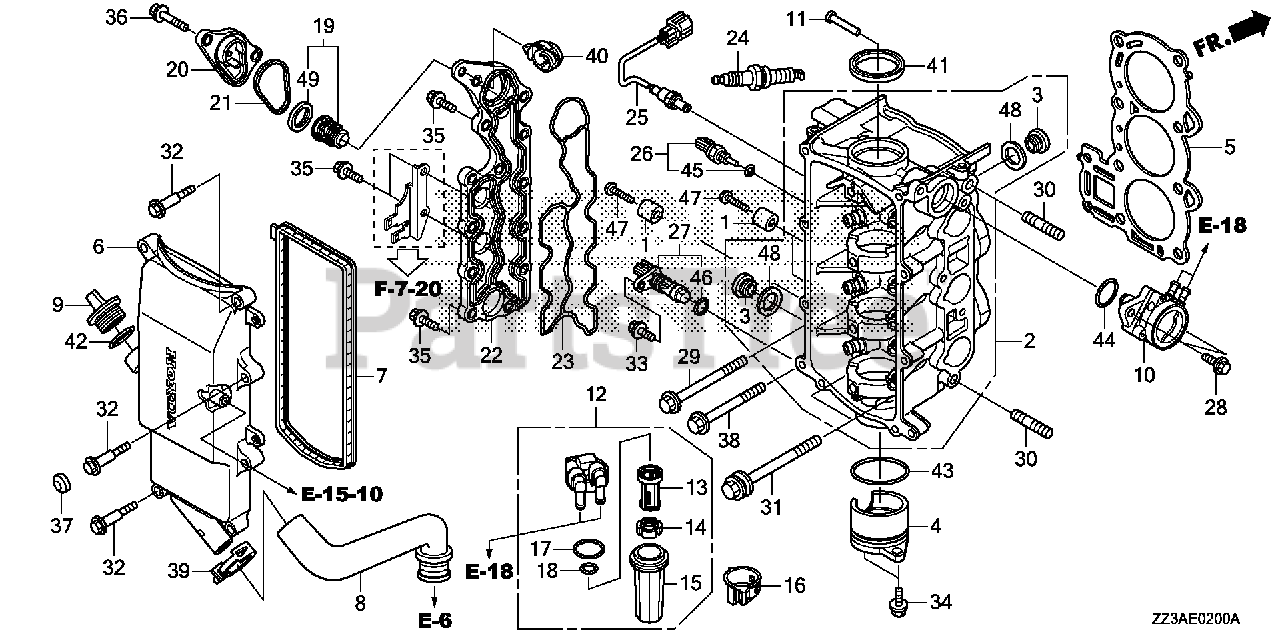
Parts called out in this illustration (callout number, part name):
1	METAL, ANODE
2	CYLINDER HEAD *NH8* (DARK GRAY)
3	BOLT, SEALING (20MM)
4	COVER, CAM THRUST
5	GASKET, CYLINDER HEAD
6	COVER, CYLINDER HEAD
7	GASKET, HEAD COVER
9	CAP, OIL (YELLOW)
10	PUMP ASSY., FUEL (MSDS)
11	LIFTER, FUEL PUMP
12	FILTER ASSY., FUEL
16	SUSPENSION, STRAINER
19	THERMOSTAT ASSY.
20	COVER, THERMOSTAT
21	O-RING, THERMOSTAT COVER
22	COVER, WATER JACKET
23	GASKET, EX. WATER JACKET COVER
24	SPARK PLUG (LMAR6C-9)
25	SENSOR, OXYGEN
26	SENSOR ASSY., WATER TEMPERATURE
27	SENSOR ASSY., TDC
28	BOLT, FLANGE (6X22)
29	BOLT, FLANGE (8X90)
30	BOLT, STUD (8X32)
31	BOLT-WASHER (9X105)
32	BOLT, HEAD COVER
33	BOLT, FLANGE (6X16)
34	BOLT, FLANGE (6X20)
35	BOLT, FLANGE (6X22)
36	BOLT, FLANGE (6X37)
37	CAP, BOLT (6MM)
38	BOLT, FLANGE (8X70)
39	CLAMP, TUBE (D29)
40	CLIP, WIRE HARNESS (25MM)
41	OIL SEAL (35X52X8)
42	O-RING (26X2.7)
43	O-RING (46.8X2.2) (NOK)
44	O-RING (31.2X2.4)
45	O-RING (9.5X1.9)
46	O-RING (15X1.9)
47	SCREW, PAN (5X20)
48	WASHER, DRAIN PLUG (20MM)
49	RUBBER, RING
